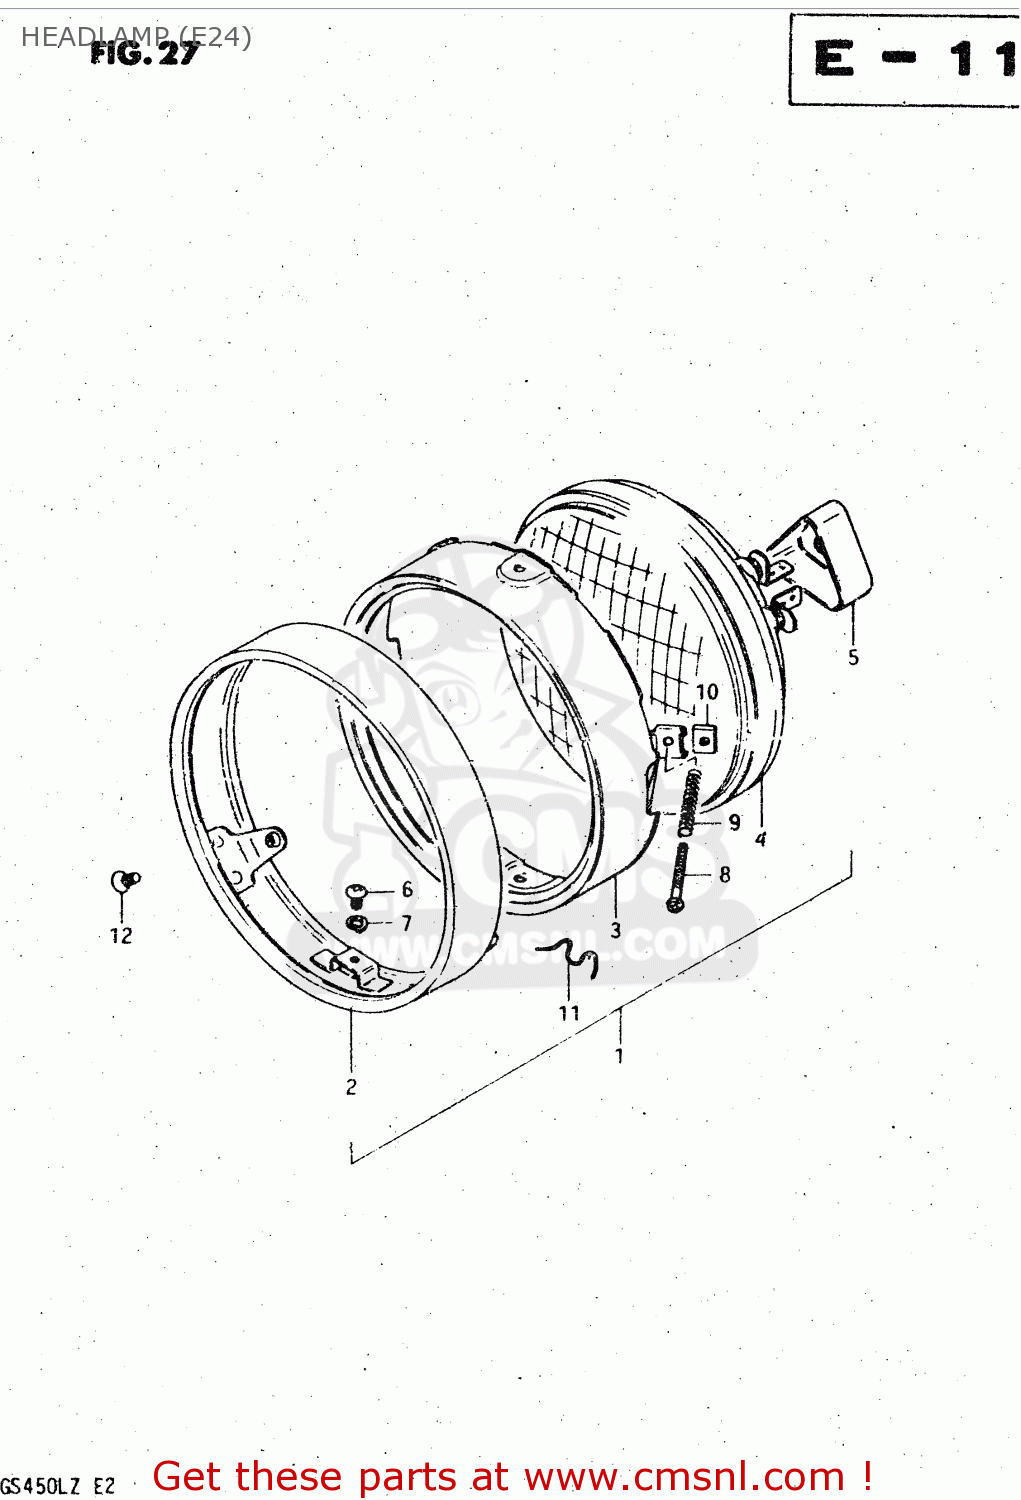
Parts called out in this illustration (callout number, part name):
1	LAMP ASSEMBLY,HEAD
2	RIM
3	RETAINER
4	LAMP UNIT
5	COVER
6	SCREW
7	LOCK WASHER
8	SCREW
9	SPRING
10	NUT
11	SPRING,HEAD LAMP UNIT
12	SCREW(5X12)
